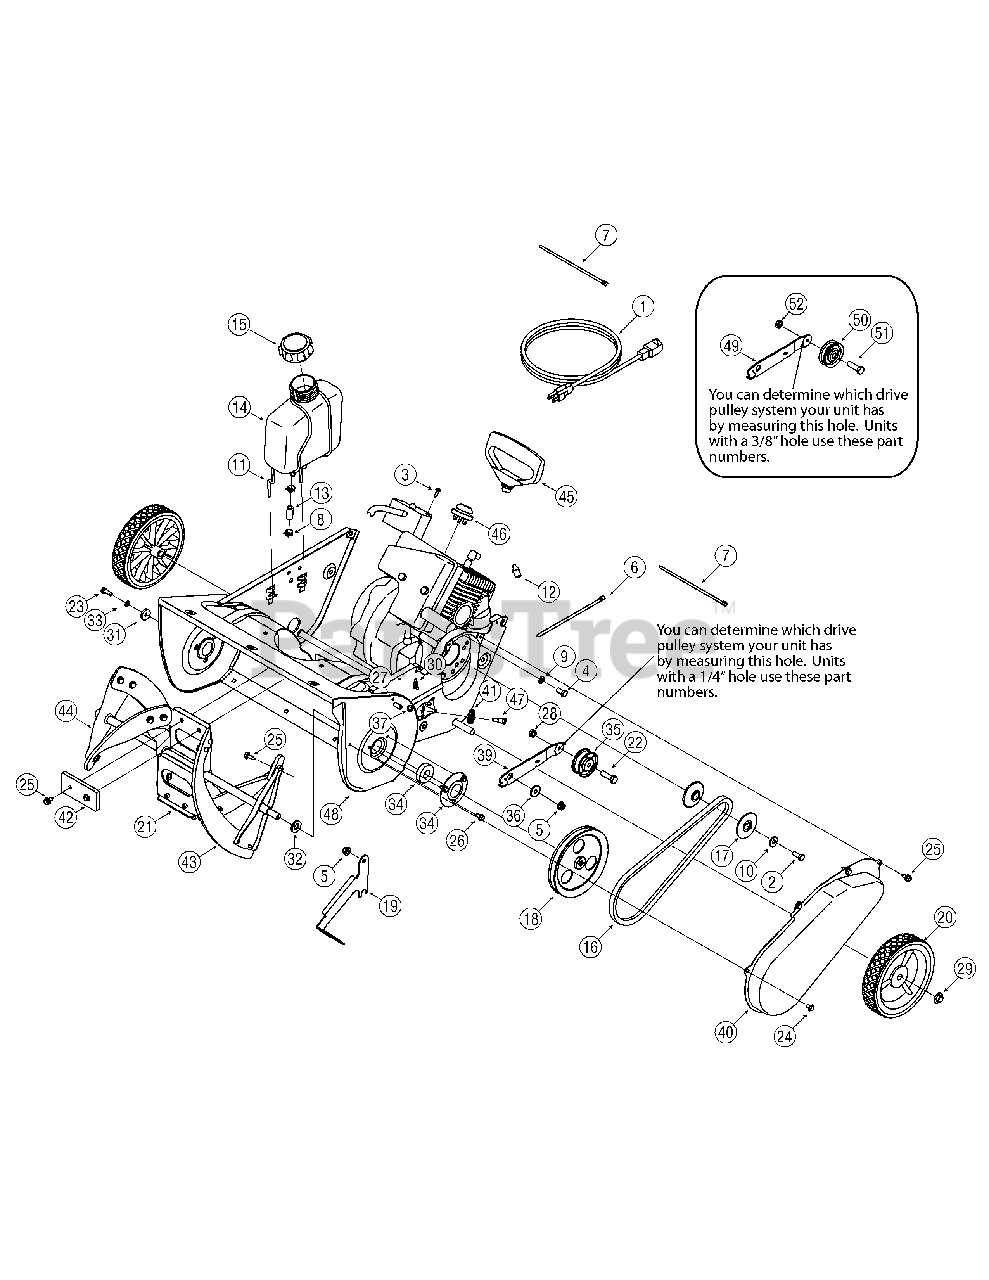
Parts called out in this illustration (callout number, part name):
1	Extension Cord
2	Hex Screw, 5/16-24 x .75
3	Screw, #10-16 x .625
4	Hex Screw, 5/16-18 x .625
5	Hex Flange Lock Nut, 5 1/16-18
6	Push Mount Cable Tie
7	Push Mount Cable Tie
9	Washer, Lock 5/16
10	Flat Washer .349 x .879 x .063
11	Gas Tank Support Wire
12	Choke Lever Knob
13	Hose, Fuel Line
14	Tank, Fuel
15	Cap, Fuel
16	V-Belt, 1/2
17	Pulley Half, .625 ID x 2.25 OD
18	Pulley, 1/2 V 1/2-20 LH x 6.0
21	Auger Assembly Complete
22	Hex Screw, 1/4-20 x 1.00 Gr.5
23	Hex Screw 1/4-20 x .75 Gr. 5
24	Self-tapping Screw 1/4-20 x x 3.75
25	Hex Screw, 1/4-14 x 0.625"
26	Self-tapping Screw, 1/4-14 x .50
27	Hex Screw 5/16-18 x .75
28	Hex Flange Lock Nut, 1/4-20
29	Push Cap, 1/2"
30	Extension Spring
31	Flat Washer .265 x .938 x.120
32	Flat Washer .510 x 1.0 x1.25
33	Lock Washer, 1/4
34	Ball Bearing 17 x 40 x 12
35	Idler Pulley (Pulley hole 1/4")
36	Shoulder Spacer .25
37	Hex Lock Nut 1/4-28
41	Cable Roller
42	Rubber Paddle
43	Crescent Spiral
45	Recoil Handle, Mitten
46	Primer
47	Carriage Screw 1/4-28
49	Idler Brkt. w/ Brake (Pulley hole 38")
50	Idler Pulley (3/8" hole)
51	Hex Screw 3/8-24 x 1.25
52	Jam Lock Nut 3/8--24
